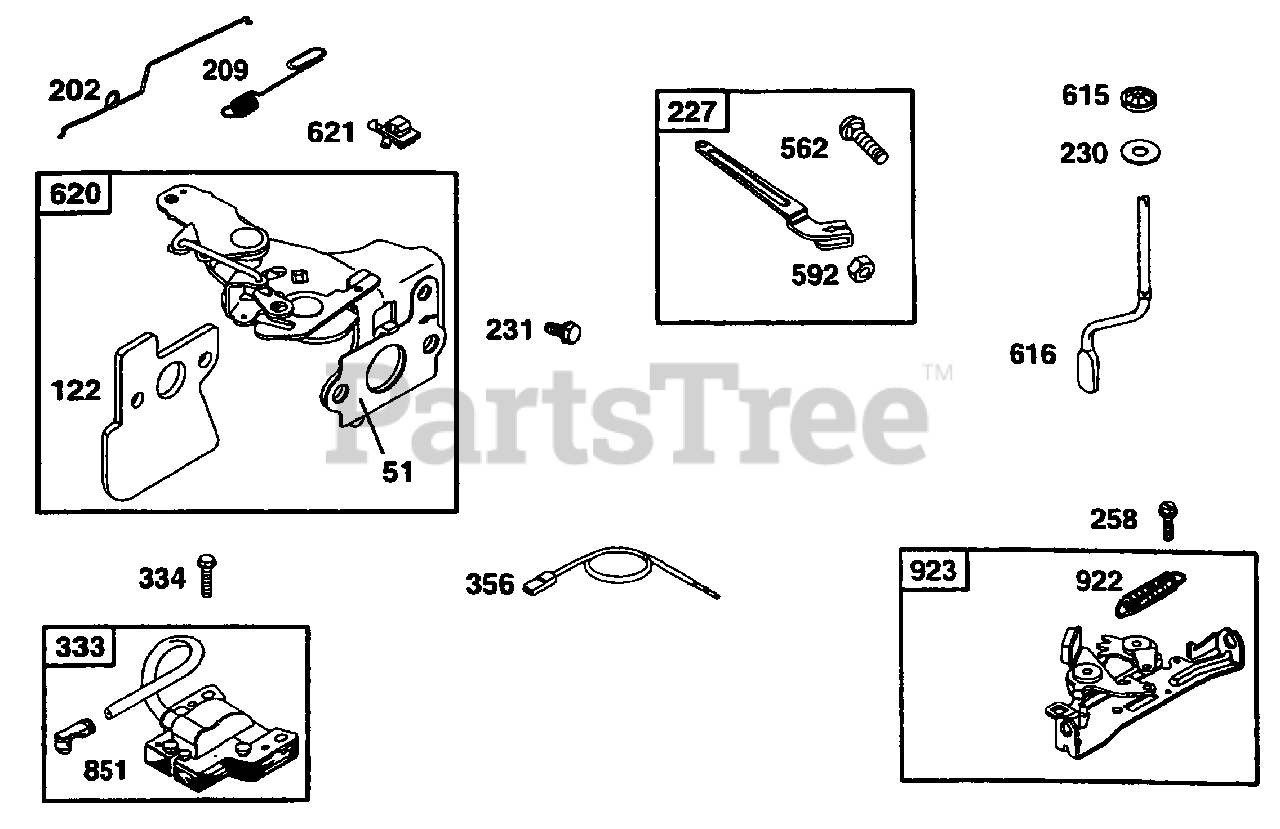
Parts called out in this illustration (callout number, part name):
51	Intake Gasket
122	Carburetor Spacer
202	Mechanical Gov Link
209	Gov. Spring
227	Gov. Lever
230	Flat Washer
258	Slotted Hex Screw
333	Magneto
334	Screw Hex
356	Stop Wire
562	Gov. Lever Bolt
615	Gov. Retainer
616	Gov. Crank
620	Control Bracket
851	Cable Terminal
922	Brake Spring
923	Brake
